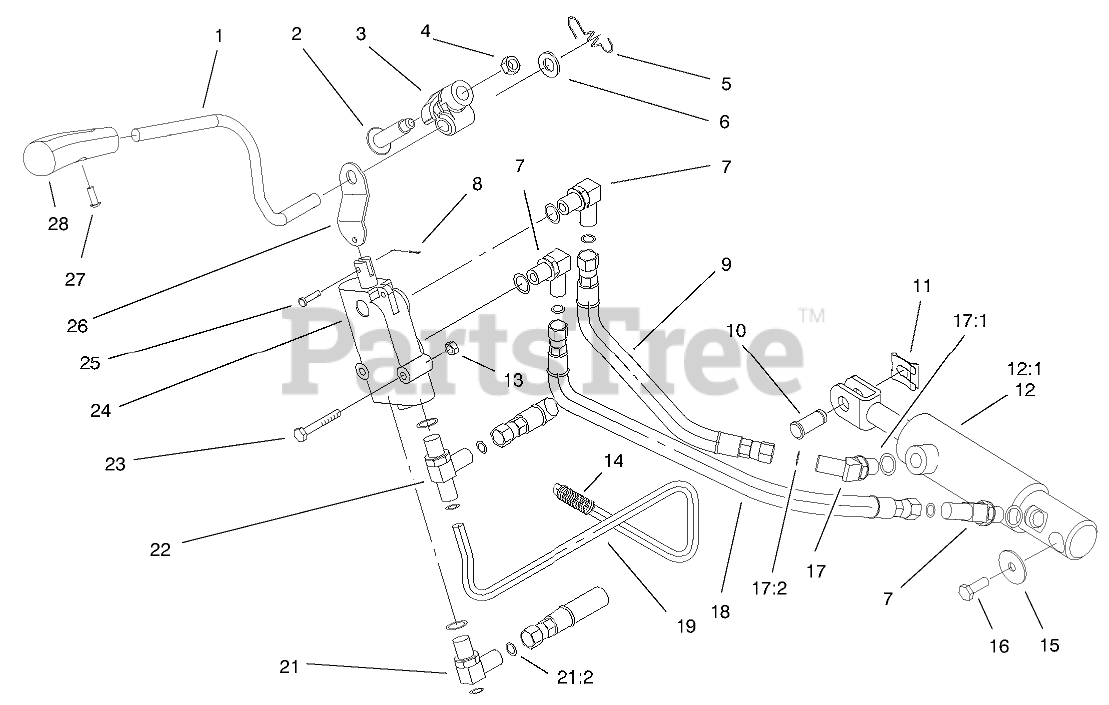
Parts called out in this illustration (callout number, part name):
1	HANDLE-LIFT
2	BOLT-SHOULDER
3	TRUNNION-LEVER, LIFT
4	NUT-JAM, LOCKING
5	SPRING-EXTENSION, LIFT
6	WASHER
7	FITTING-HYD, 90 DEGREE
8	PIN-COTTER
9	HOSE ASM
10	PIN-CLEVIS
11	CLIP-PIN
12	LIFT CYLINDER ASM
12:1	KIT-SEAL
13	NUT-LOCK, NI
14	COVER-BRACE
15	WASHER-FLAT
16	SCREW-THREAD LOCKING
17	FITTING-HYD, 45 DEGREE
17:1	O-RING
17:2	O-RING
18	HOSE ASM
19	TUBE-HYD
21	FITTING-HYD, 90 DEGREE
22	FITTING-HYD, TEE
23	SCREW-HH
24	VALVE-HYD
25	PIN-CLEVIS
26	LINK-LIFT
27	SCREW-PPHTF
28	Knob-Lift (Int-l)(Only On: 73590)
28	Knob-Lift (Only On: 73552)
